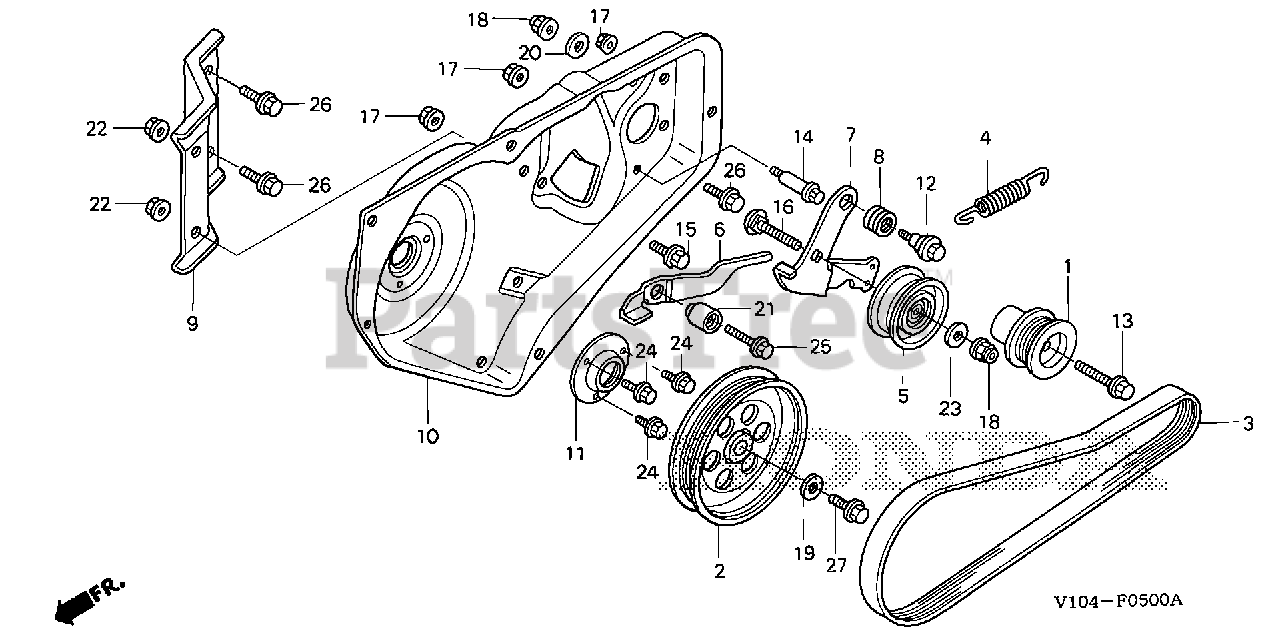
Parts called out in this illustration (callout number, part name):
1	PULLEY, DRIVE
2	PULLEY, DRIVEN
3	V-BELT, RIBBED
4	SPRING, TENSIONER ARM
5	ROLLER, TENSIONER
6	ARM, AUGER BRAKE
7	ARM, TENSION
8	SPRING, TENSIONER ARM BOLT
9	BRACKET, BELT COVER STAY
10	COVER, BELT (INNER)
11	HOLDER, L. AUGER (BEARING)
12	BOLT, TENSIONER ARM
13	BOLT, FLANGE (5/16-24X1")
14	BOLT, BELT GUIDE
15	BOLT, SIDE COVER
16	BOLT, PAN (8X35)
17	NUT, SELF-LOCK (6MM)
18	NUT, FLANGE (M8X1.25) (SELF-LOCK)
19	WASHER (8MM)
20	WASHER (8.5X26)
21	COLLAR, BRAKE ARM
22	NUT, FLANGE (8MM)
23	WASHER, PLAIN (8MM)
24	BOLT, FLANGE (6X10)
25	BOLT, FLANGE (6X28)
26	BOLT, FLANGE (8X16)
27	BOLT, FLANGE (8X20)
